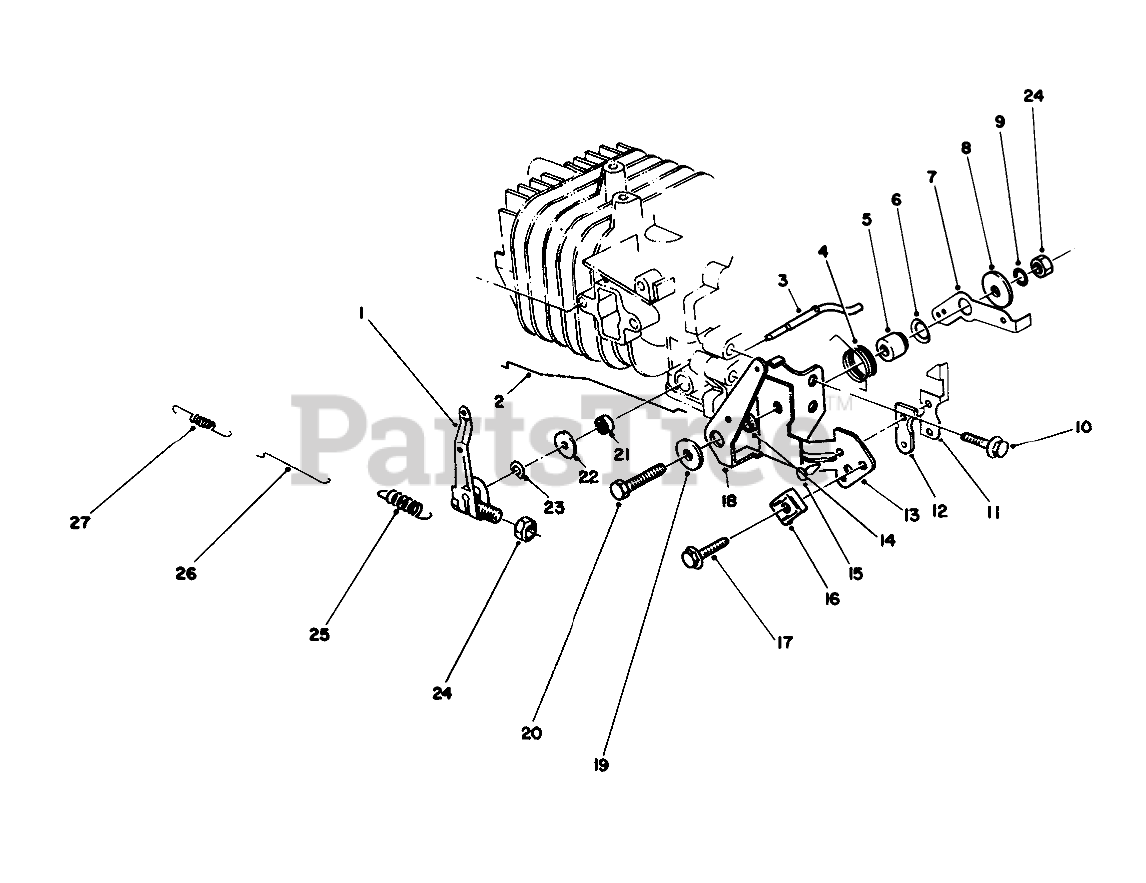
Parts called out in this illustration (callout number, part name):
1	ARM-GOVERNOR
2	ROD-CHOKE
3	Shaft-Govemor
4	SPRING-CHOKE LEVER
5	Gov Lever Spacer
6	Washer-Gov. Spring Lever
7	LEVER-SPRING, GOVERNOR
8	WASHER
9	LOCKWASHER
11	TERMINAL-KILL SWITCH
12	INSULATOR-KILL SWITCH
13	BRACKET-THROTTLE, CONTROL
14	SPACER-CHOKE LEVER
15	KILL SWITCH RIVET
16	CLAMP
18	LEVER-CONTROL, CHOKE
19	WASHER
21	SEAL-OIL
22	WASHER
23	E-RING
25	SPRING-GOVERNOR
26	ROD-CARBURETOR
27	SPRING
